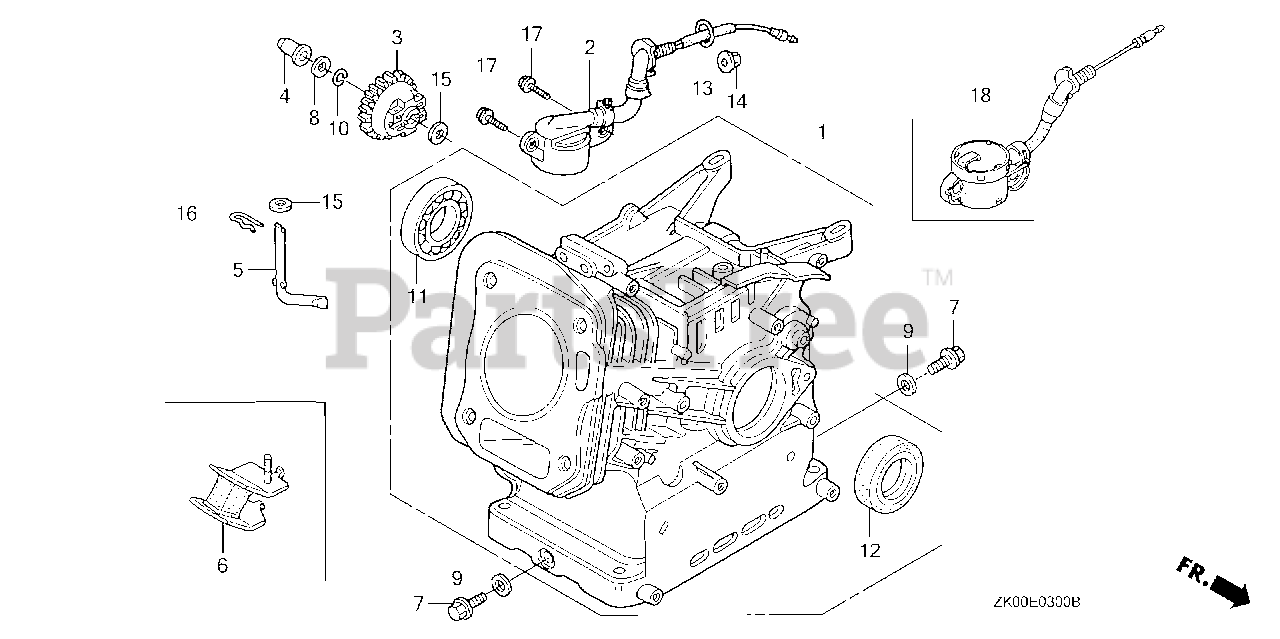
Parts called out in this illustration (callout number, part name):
1	CYLINDER ASSY.
2	SWITCH ASSY., OIL LEVEL
3	GOVERNOR ASSY.
4	SLIDER, GOVERNOR
5	SHAFT, GOVERNOR ARM
7	BOLT, DRAIN PLUG
8	WASHER, THRUST (6MM)
9	WASHER, DRAIN PLUG (10.2MM)
10	CLIP, GOVERNOR HOLDER
11	BEARING, RADIAL BALL (6205TMB) (NTN)
12	OIL SEAL (25X41X6) (NOK)
13	O-RING (13.5X1.5) (ARAI)
13	O-RING (14MM) (NOK)
14	NUT, FLANGE (10MM)
15	WASHER, PLAIN (6MM)
16	PIN, LOCK (8MM)
17	BOLT, FLANGE (6X12)
